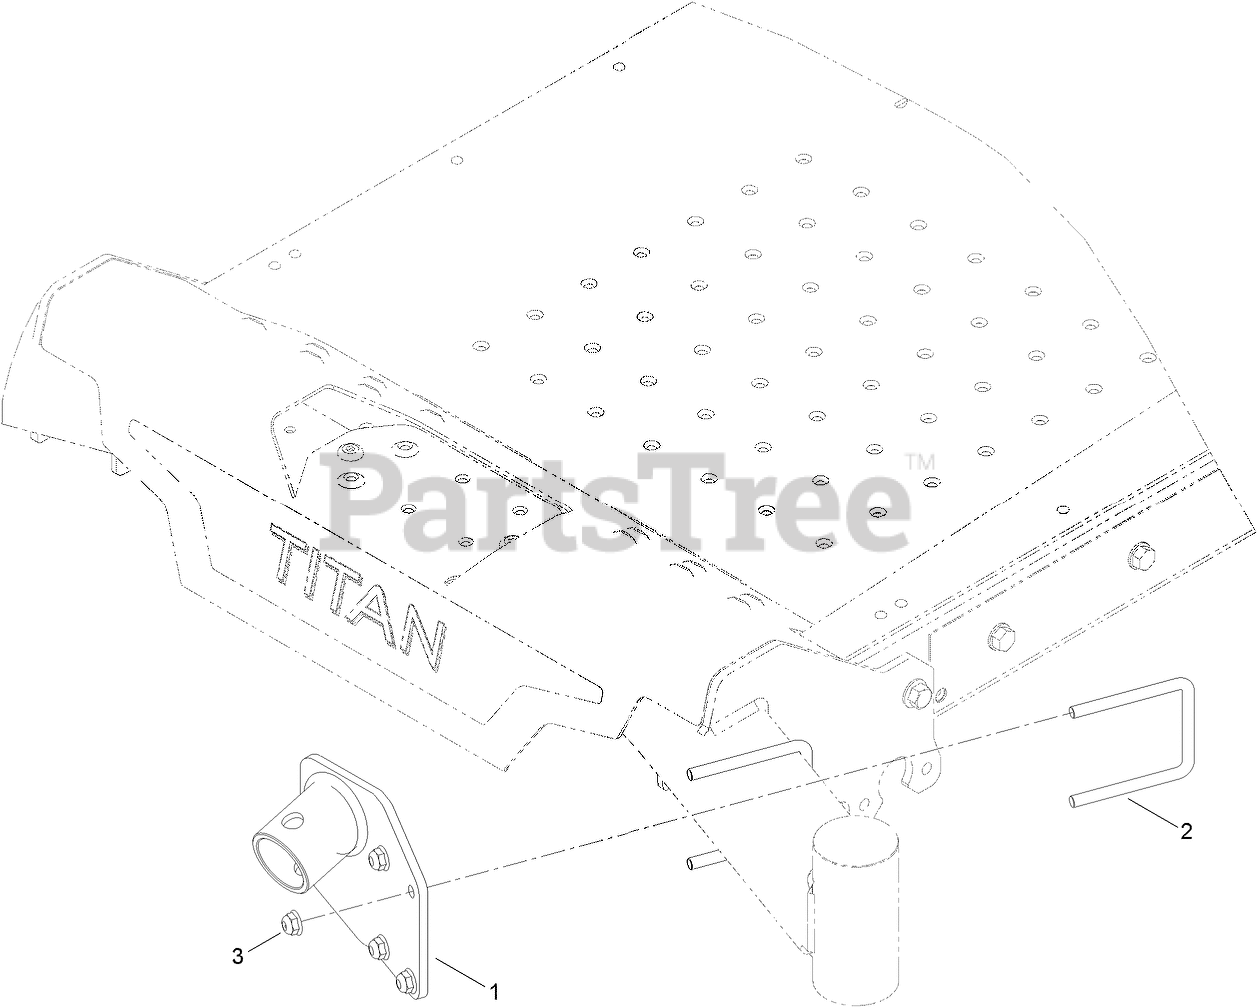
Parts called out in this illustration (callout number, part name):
1	JACK MOUNT ASM
2	U-BOLT
3	NUT-HF
